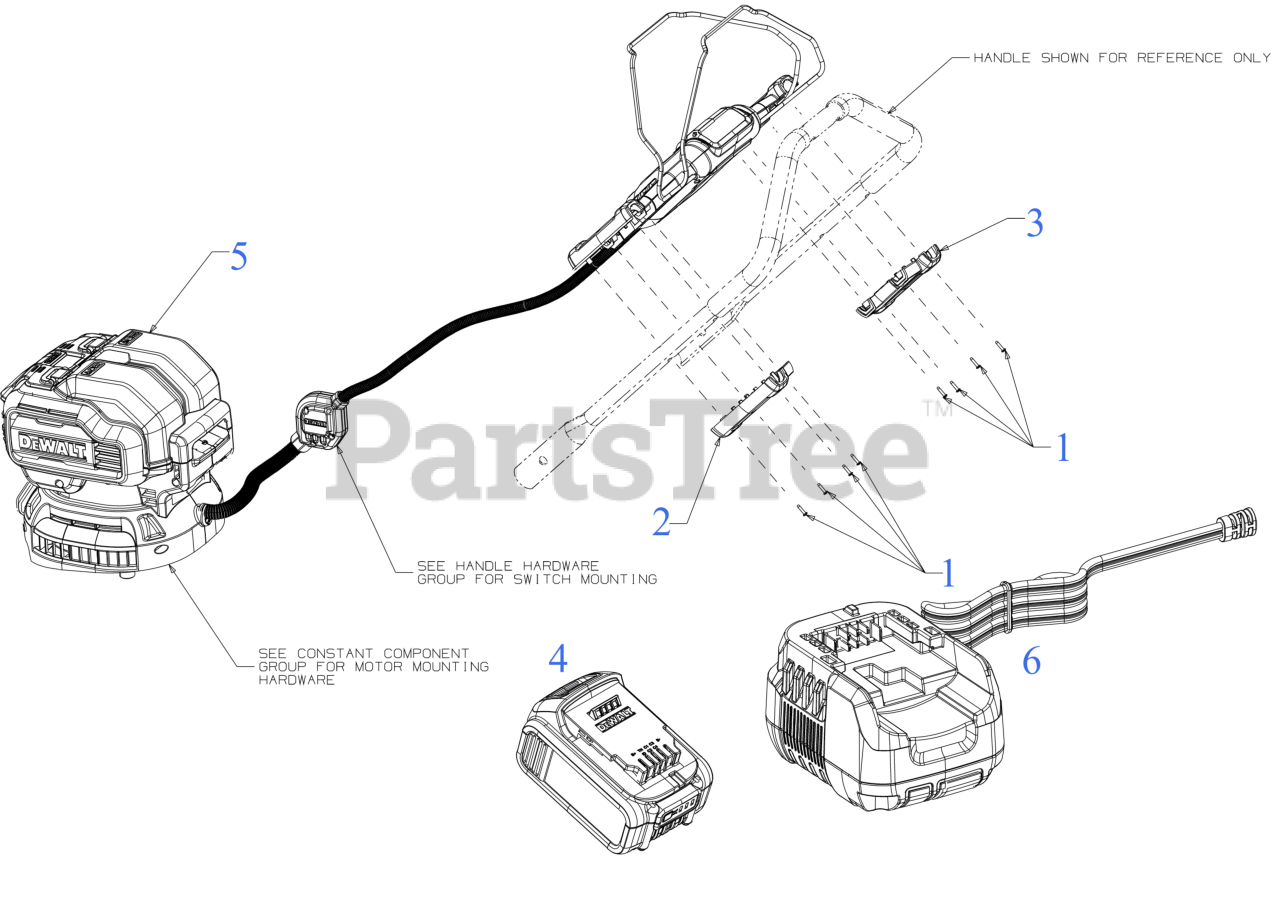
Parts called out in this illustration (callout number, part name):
1	SCREW-TAP PLASTIC #6-19 x 0.63
2	HANDLE PANEL COVER (REAR) (LH) (YELLOW)
3	HANDLE PANEL COVER (REAR) (RH) (YELLOW)
4	BATTERY (10AH 20V)
5	MOTOR/PANEL ASSEMBLY
6	CHARGER (DCB1102)
